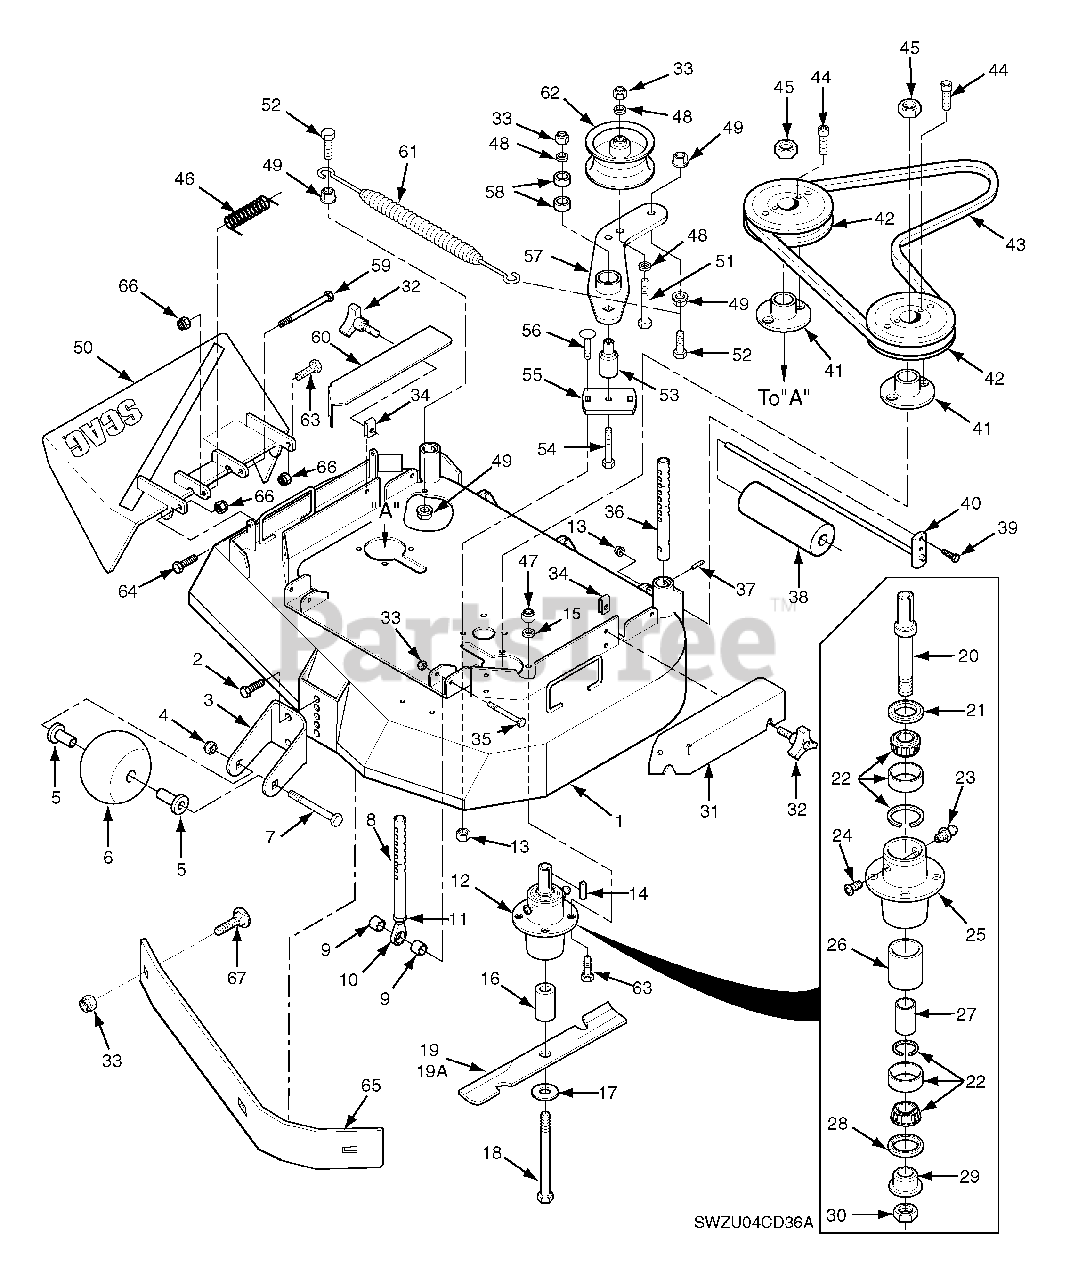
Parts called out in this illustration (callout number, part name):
1	Cutter Deck
2	Capscrew, 3/8-16 x 1.0" Serrated Flange Hex Hd
3	Bracket, Anti-Scalp Wheel
4	Lock Nut, 3/8-16 Center Lock
5	Bushing, .376" ID Oilite
6	Wheel, Anti-Scalp
7	Bolt, Carriage 3/8-16 x 4"
8	Pin Assy., Deck Adj.
9	Spacer, Deck Adjustment Pin
10	Rod End, Male 3/8-24 RH Thread
11	Nut, 3/8-24 Jam
12	Spindle Assembly
13	Nut, 5/16-18 Serrated Flange
14	Key,1/4" x 1/4" x 2"
15	Lock Washer 5/16"
16	Spacer, Spindle
17	Flatwasher, 5/8 W
18	Bolt, Hex Head 5/8-11 x 9-1/2"
19	Cutter Blade, 18"
19A	Cutter Blade, 18" Hi Lift
20	Spindle Shaft
21	Seal, Cutter Spindle Top
22	Tapered Bearing Set (Two Bearings W/Race)
23	Grease Fitting
24	Relief Fitting, Cutter Spindle
25	Spindle Housing
26	Spacer, Outside
27	Spacer, Inside
28	Seal, Cutter Spindle Bottom
29	Spindle Bushing
30	Nut, Spindle
31	Belt Cover, LH
32	Wing Nut, 3/8-16
33	Nut, 3/8-16 Elastic Stop
34	U-Nut, 3/8-16
35	Bolt, Hex Head 3/8-16 x 2-1/2"
36	Pin, Deck Adj. Rear
37	Pin, Sloted Spring 3/16 x 1-1/2"
38	Guide, Roller
39	Bolt, Hex Head 5/16-18 x 1"
40	Roller Shaft
41	Tapered Hub
42	Pulley
43	Belt, Cutter Deck
44	Capscrew, Socket Head. 1/4-20 x 1-3/8"
45	Hex Nut, 5/8-11
46	Spring, Chute Return
47	Lock Nut, 5/16-18 Elastic Stop Grade 8
48	Flatwasher, 3/8" (.938 x .391 x .105)
49	Nut, 3/8-16 Serrated Flange
50	Discharge Chute
51	Capscrew, Hex Head 3/8-16 x 3-3/4"
52	Capscrew, Hex Head 3/8-16 x 1-1/2"
53	Pivot, Idler - Long
54	Capscrew, Hex Head 38/16 x 3-1/4"
55	Base, Idler Pivot
56	Bolt, Carriage 5/16-18 x 1"
57	Idler Arm Weldment
58	Ball Bearing
59	Bolt, Hex Head 5/16-18 x 4-3/4"
60	Belt Cover, RH
61	Spring, Deck Idler
62	Pulley, Idler
63	Bolt, Hex Head 5/16-18 x 1-1/2" Grade 8
64	Bolt, Hex Head 5/16-18 x 1-3/4"
65	Baffle Weldment
66	Lock Nut, 5/16-18 Elastic Stop
67	Bolt, Carriage 3/8-16 x 1"
